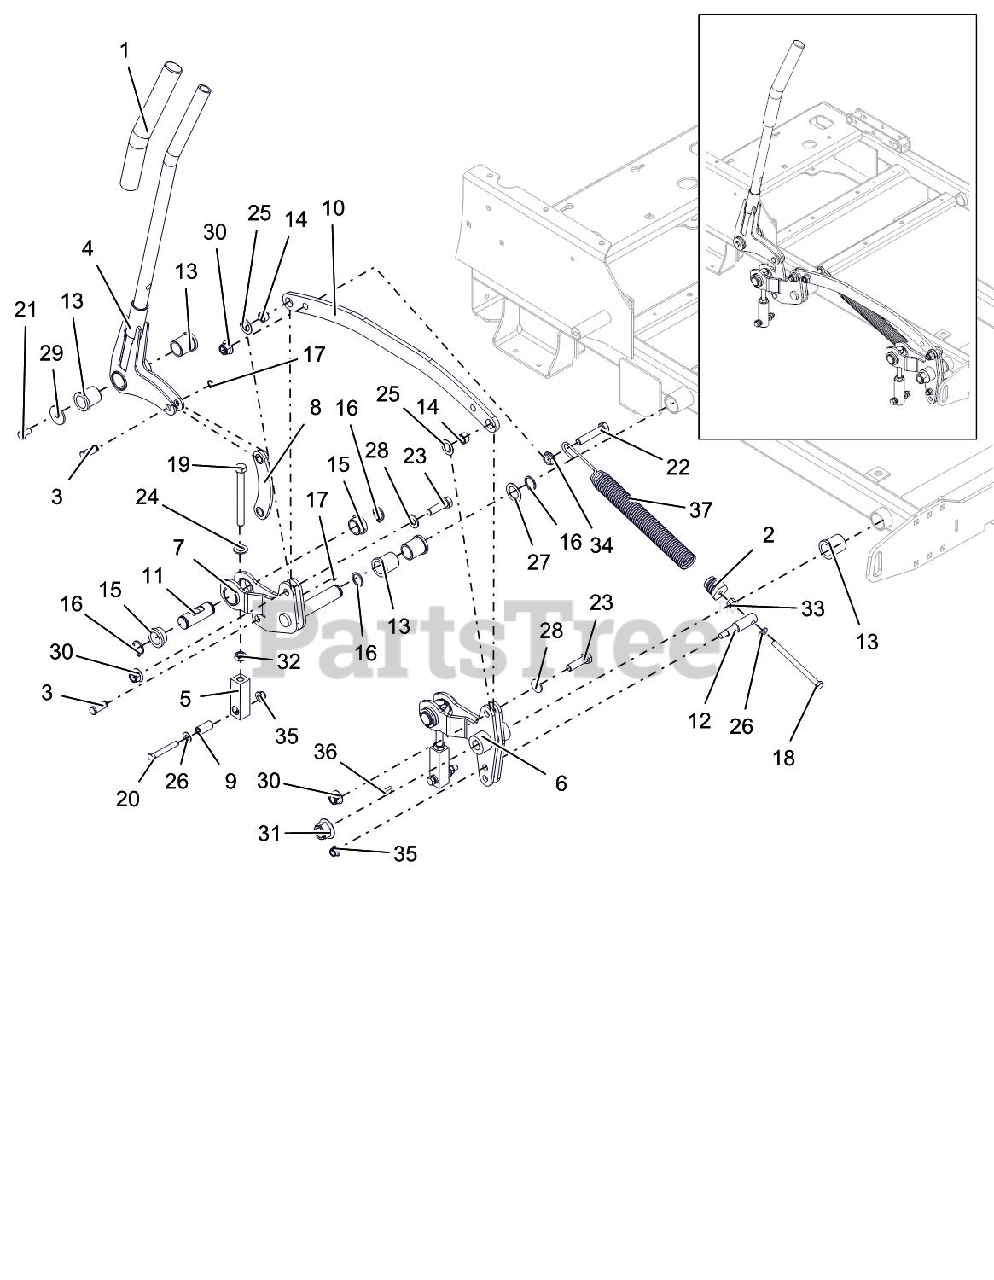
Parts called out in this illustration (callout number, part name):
1	GRIP, HANDLEBAR 1.00X1.38X11.3
2	PLUG, SPRING
3	PIN, CLEVIS .500 SNAP RING
4	WLDMT, HAND LEVER
5	LINK, DECK LIFT
6	WLDMT, PSTANCE TAPERED HUB
7	WLDMT, PSTANCE DECK ARM
8	WLDMT, DECK LIFT LINK
9	SPACER, DECK LEVELING
10	ARM, DECK LIFT
11	PIN, DECK LIFT
12	TRUNION, DECK LIFT
13	BSHG-FLG 1.00X1.25X1.50X1.50
14	BSHG-SLV .513 X .748 X .420
15	BSHG,FLG 1.0 X 1.25 X 1.5 X .6
16	RG-RTNG-EXT 1.00X.078
17	RG-RTNG-EXT .500X.050 (SNAP)
18	BLT-HEX .38-16X5.00 GR5 FTH YZ
19	BOLT, 1/2-13 X 5.0 2.5 THREAD
20	BLT-HEX .38-16X2.50 GR8 YWZC
21	@BLT-HEX .38-16X.75 GR5 YWZC
22	@BLT-HEX .50-13X2.50 GR5 YWZC
23	@BLT-HEX .50-13X1.75 GR5 YWZC
24	FLATWASHER 1/2 SAE HARD 15906
25	WSHR-HDND-THRST .758X1.23X.031
26	@WSHR-FL-STL.406X.812X.065 YWZ
27	WSHR-FL-STL 1.010X1.505X.062YZ
28	@WSHR-FL-STL.531X1.06X.095YWZC
29	WSHR-FL-STL .380X1.50X.125YWZC
30	@NUT-LK-NYL-FLG .50-13 YWZC
31	@NUT-LK-NYL-FLG .75-10 YWZC
32	NUT-JAM .50-13 YWZC
33	@NUT-HEX .38-16 YWZC
34	NUT-SPNLK-FLG .50-13 YWZC
35	@NUT-LK-NYL-FLG .38-16 YWZC
36	KEY-WDRF .25X1.00 HRD #15
37	SPRING, DECK LIFT
